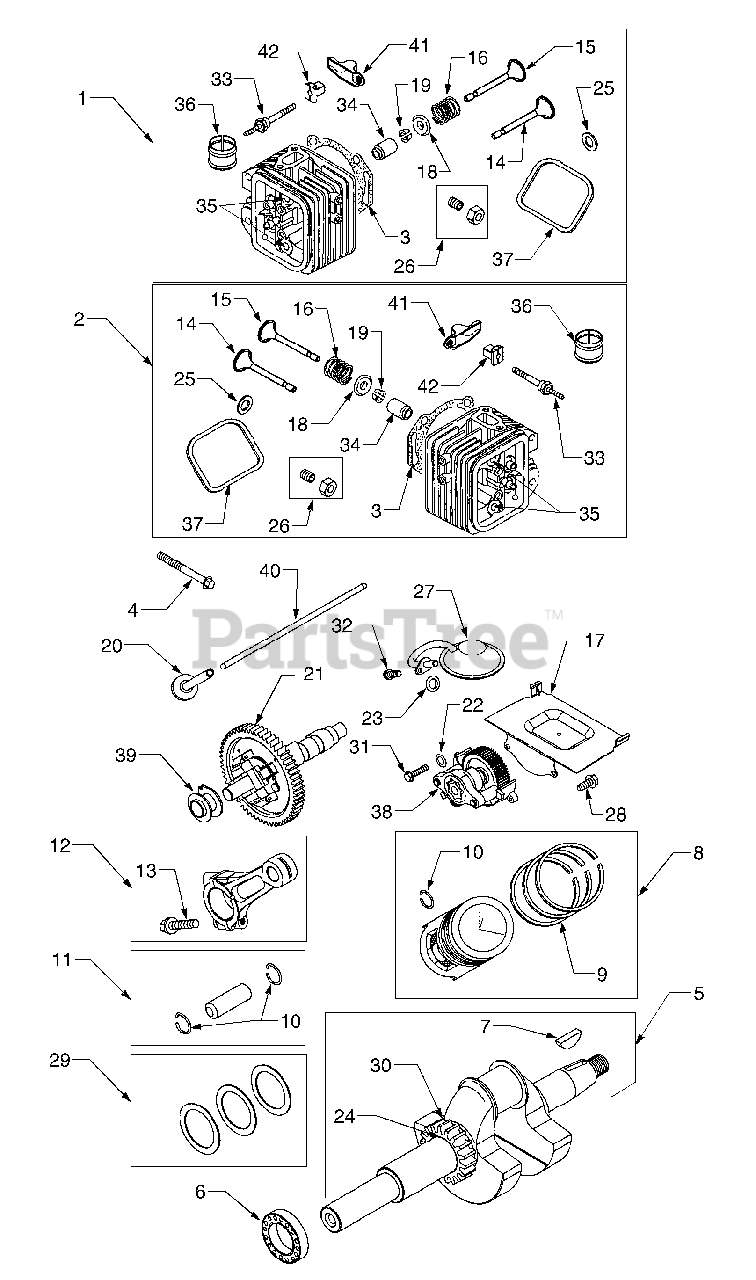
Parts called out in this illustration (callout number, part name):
1	Head, Cylinder #1
2	Head, Cylinder #2
3	Gasket, Cylinder Head
4	Screw, Cylinder Head
5	Crankshaft
6	Bearing, Ball
7	Key, Flywheel
8	Piston Assembly (Standard)
9	Ring Set, Piston (Standard)
10	Lock, Piston Pin
11	Pin Assembly, Piston
12	Rod Assembly, Connecting
13	Screw, Connecting Rod
14	Valve, Exhaust
15	Valve, Intake
16	Spring, Valve
17	Deflector, Oil
18	Retainer, Valve Spring
19	Retainer, Valve (2)
20	Tappet, Valve
21	Gear, Cam
22	Seal, O-Ring
23	Seal, O-Ring
24	Key, Timing
25	Washer
26	Screw, Valve Adjustment
27	Screen, Oil Pump
28	Screw, Hex
29	Washer Set
30	Gear, Timing
31	Screw, Hex
32	Screw, Hex
33	Stud, Rocker Arm
34	Seal, Guide Bushing
35	Bushing, Guide
36	Liner, Port
37	Gasket, Rocker Cover
39	Spool, Governor
40	Push Rod, Intake
41	Rocker Arm
42	Pivot, Rocker Arm
